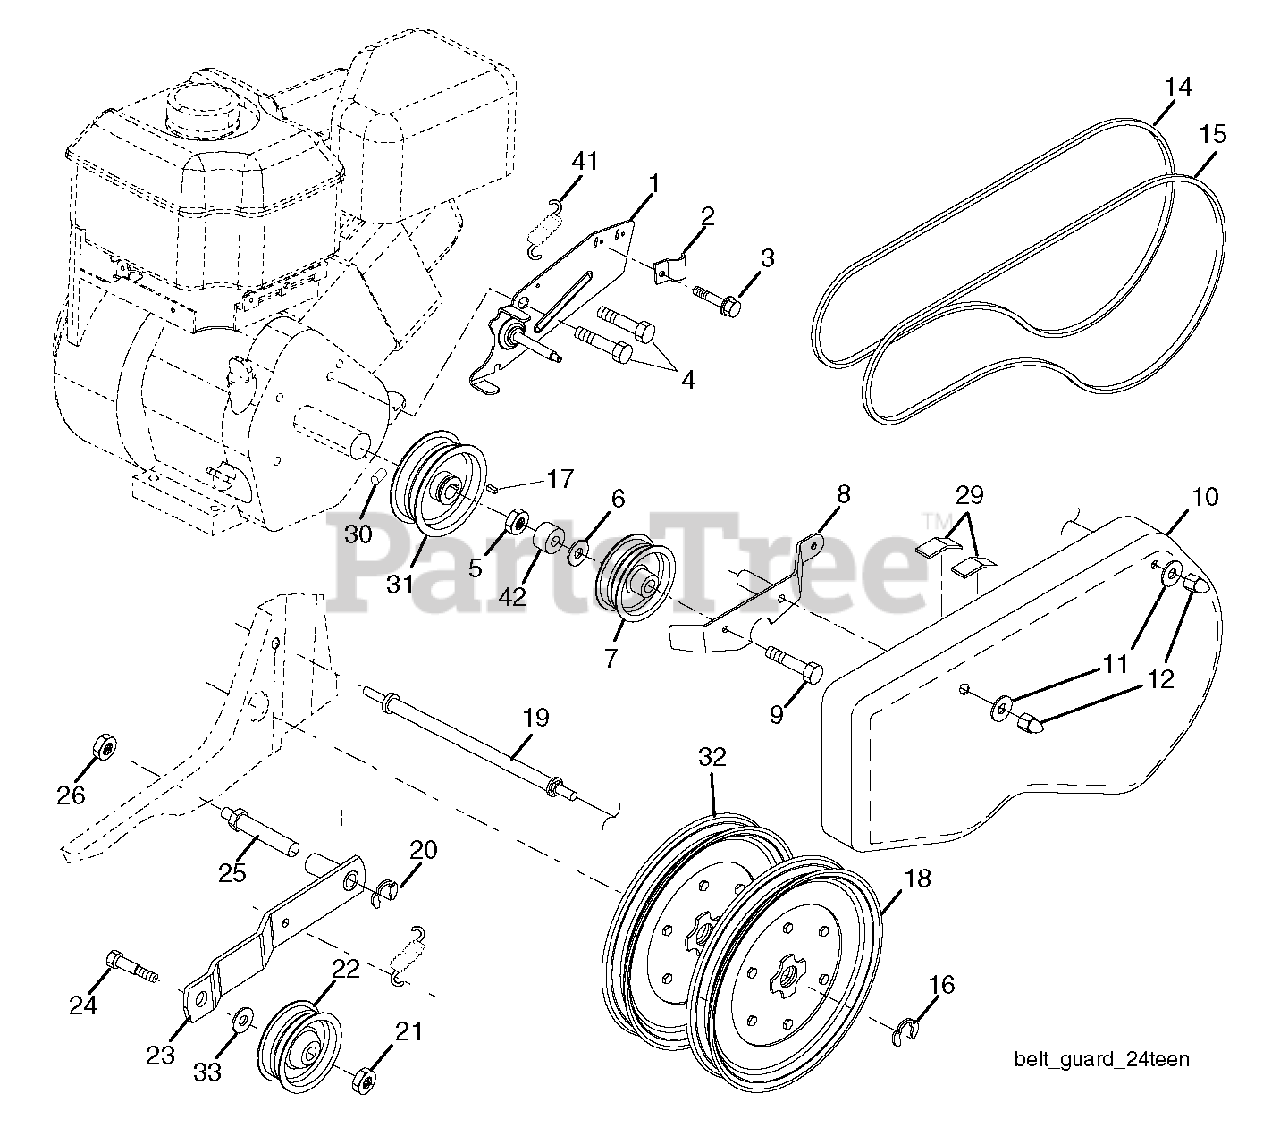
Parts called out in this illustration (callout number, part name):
1	RP ASSEMBLY,BRACKET,BELTGUARD
2	CLIP.PLATED
3	SCREW.HXTAP.10-24
5	NUT, LOCK 5/16-18
6	Axle Bushing Spacer
7	Flat Idler Pulley
8	ARM.ASM.REV.IDLER.TILL.BLACK
11	WASHER
12	CAP
15	BELT.TILLER.DRIVE
16	RETAINING RING LT
18	SHEAVE,TRANS."D"
19	BOLT.BELT.GUARD
20	KLIP RING TI
21	NUT, LOCK 5/16-18
22	PULLEY.W/SPACER.2.25
23	ARM.ASM.IDLER.PNT
24	HEX BOLT
25	SHAFT.IDLER.TILLER
26	JAM NUT TI
29	PAD IDLER TI
32	SHEAVE.TRANS
33	WASHER.20X8.5
41	SPRING.EXTENSION
42	SPACER.CONTROL.LEVER
